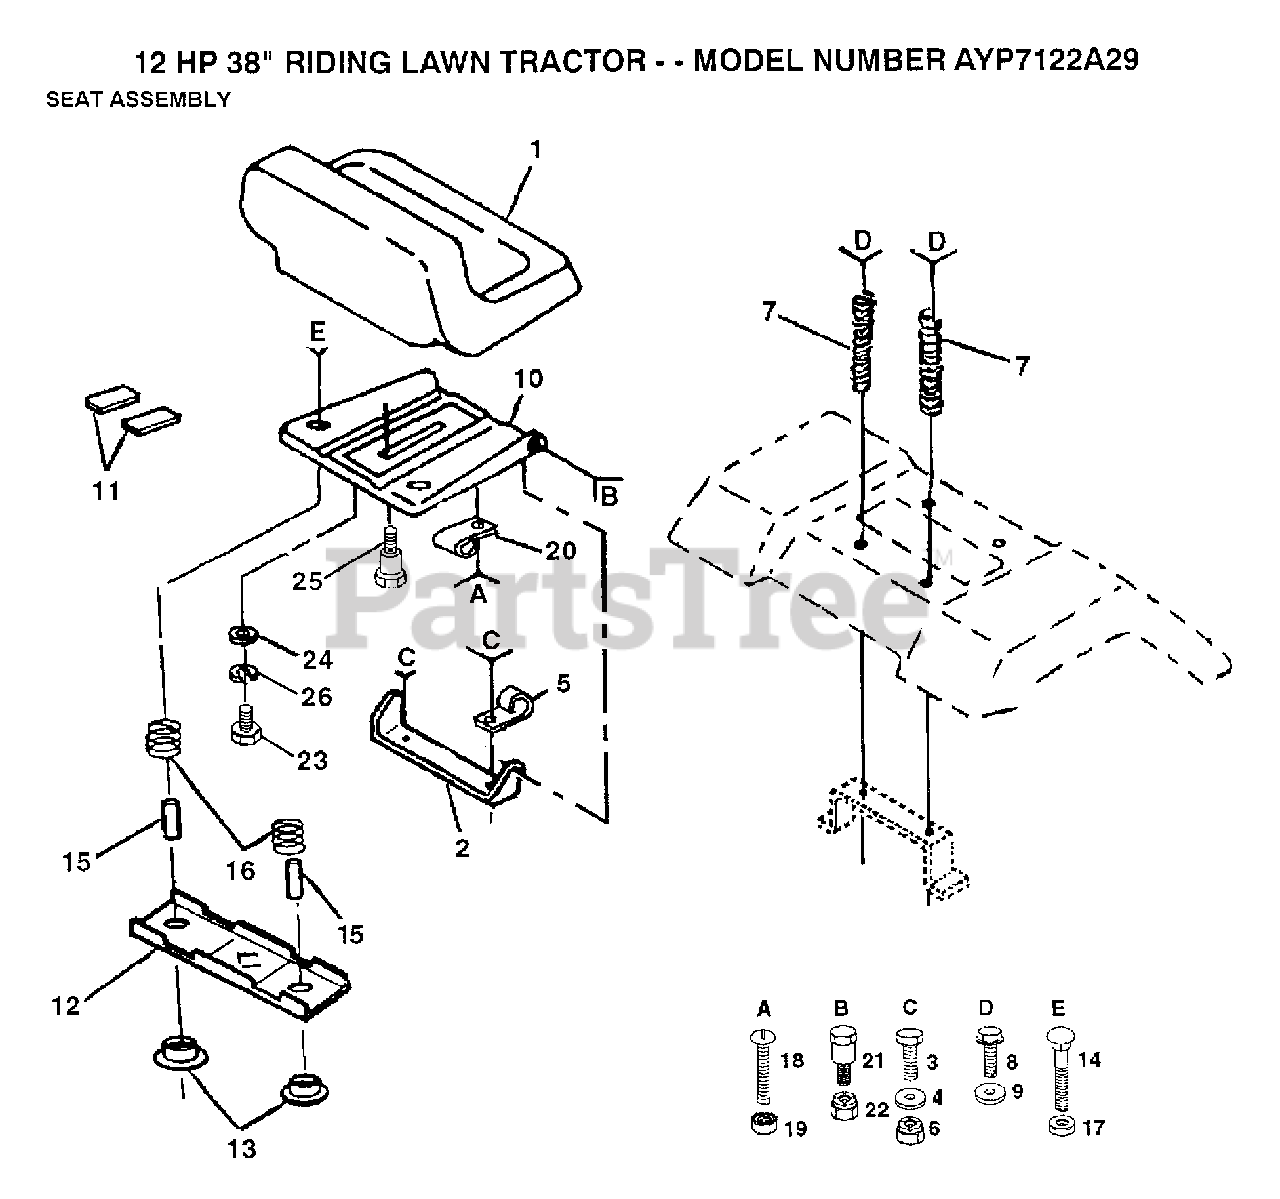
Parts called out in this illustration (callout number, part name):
4	WASHER
5	CLIP T
7	SPRING COMPRESSIO
8	SCREW GTV
9	WASHER
11	STRIP FORM
12	BRKT SWITCH
13	BUSHING
15	SPACER SPLIT
16	SPRING
19	"NUT,KEPS"
23	BOLT
24	WASHER
25	"BOLT,SHOULDER"
26	LOCKWASHER
